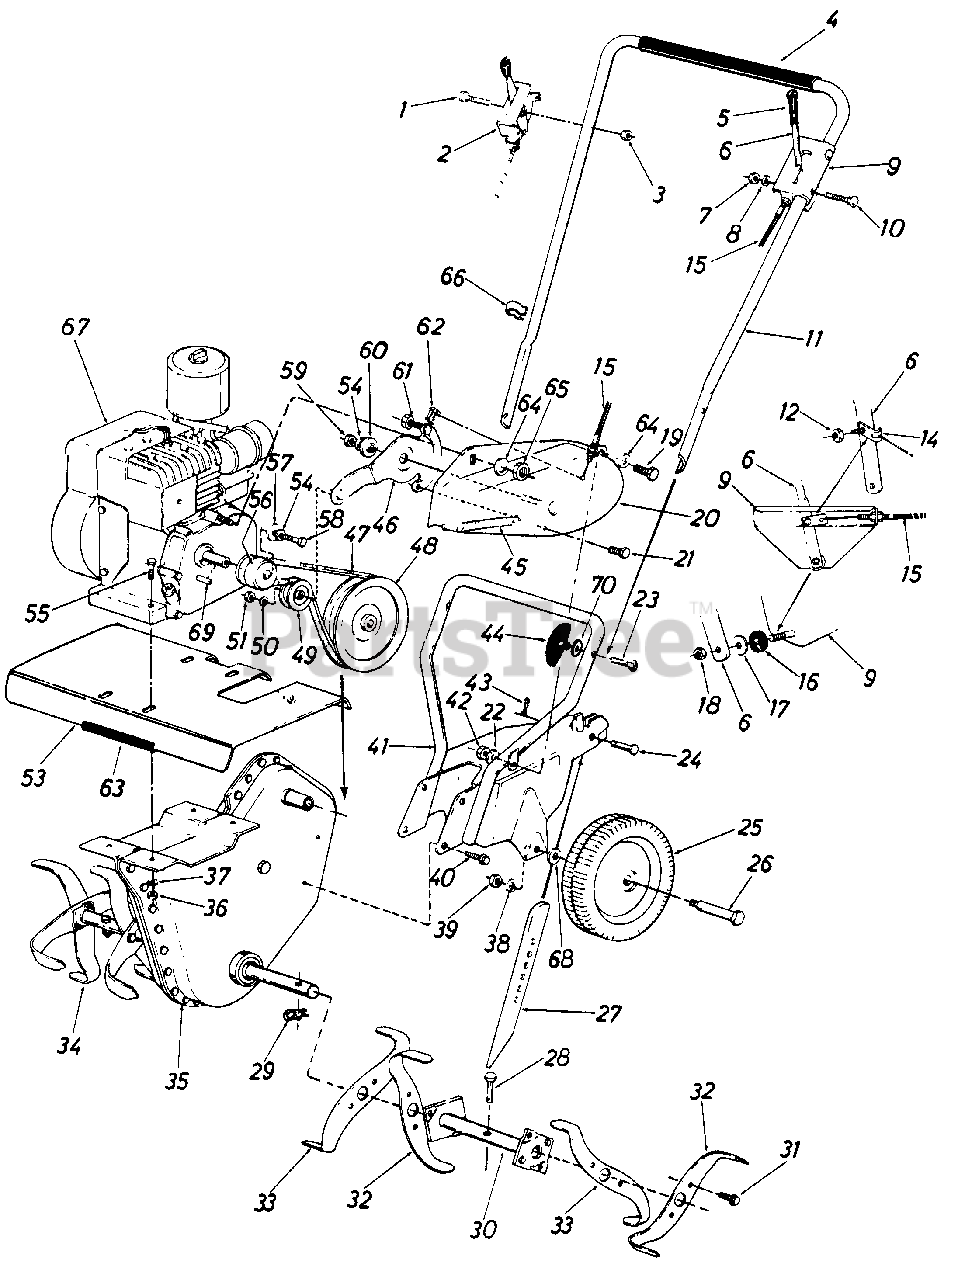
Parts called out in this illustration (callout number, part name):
1	Hex Bolt 1/4-20 x 1.50" Lg.
2	Throttle Control Ass'y. Comp.
3	Hex Cent. L-Nut 1/4-20 Thd.
4	Grip-14" Lg.
5	Handle Grip
6	Clutch Handle Ass'y.
7	Hex Cent. L-Nut 1/4-20 Thd.
8	Fl-Wash. 1/4" I.D. x .50" O.D. x .063
9	Clutch Handle Brkt. Ass'y.
10	Carr. Bolt 1/4-20 X 1.25" Lg.
11	Upper Handle
12	Hex Cent. L-Nut 1/4-20 Thd.
15	Clutch Cable
16	Rubber Wash.
17	Fl-Wash. 1/4" I.D. x .75" O.D. x .063
18	Hex Cent. L-Nut 1/4-20 Thd.
19	Hex Bolt 1/4-20 x .75" Lg.
20	Belt Cover Ass'y.
21	Hex Wash. Hd. Tap Scr. 1/4 x .50"
22	L-Wash. 1/4" I.D.
23	Curved Hd. Bolt 5/16-18 x 1.75" Lg.
24	Clevis Pin
25	Wheel Ass'y.-7"
26	Shoulder Bolt
27	Depth Bar
28	Clevis Pin .31 Dia. x 1.5"
29	Hairpin Cotter
34	Tine Ass'y. Comp.
35	Chain Case Ass'y. Comp.
36	Hex Nut 5/16-18 Thd.
37	L-Wash. 5/16" I.D.
38	L-Wash. 3/8" Scr. H.D.
39	Hex Cent. L-Nut 3/8-16 Thd.
40	Hex Wash. SF-Tap Scr. 5/16-18 x .50" Lg.
43	Intern. Cotter Pin
44	Hand Knob
45	Extension Spring 4.88" Lg.
46	Idler Arm Ass'y.
47	Belt 318" x 29" Lg.
48	Chain Case Pulley 5-1/2 x 1/2"
49	Fl-ldler 2"
50	L-Wash. 5/16" I.D.
51	Hex Nut 3/8-24 Thd.
55	Hex Bolt 5/16-18 x 1.5" Lg.
56	Engine Pulley 3/8 V x .7525 I.D. x 2" O.D.
57	Fl-Wash. .385 I.D. x 1.00" O.D. x .135
58	Hex Bolt 3/8-24 x 1.00" Lg.
59	Hex Nut 5/16-18 Thd.
60	Shld. Spacer .50" Dia. x .133
61	Hex Cent. L-Nut 1/4-20 Thd.
63	Trim Strip-4"
64	L-Wash. 1/4" I.D.
65	Hex Cent. L-Nut 1/4-20 Thd.
66	Cable Tie
67	Engine
68	Bell-Wash.
69	Square Key 3/16 x 3/4" Lg.
70	Belleville Washer
